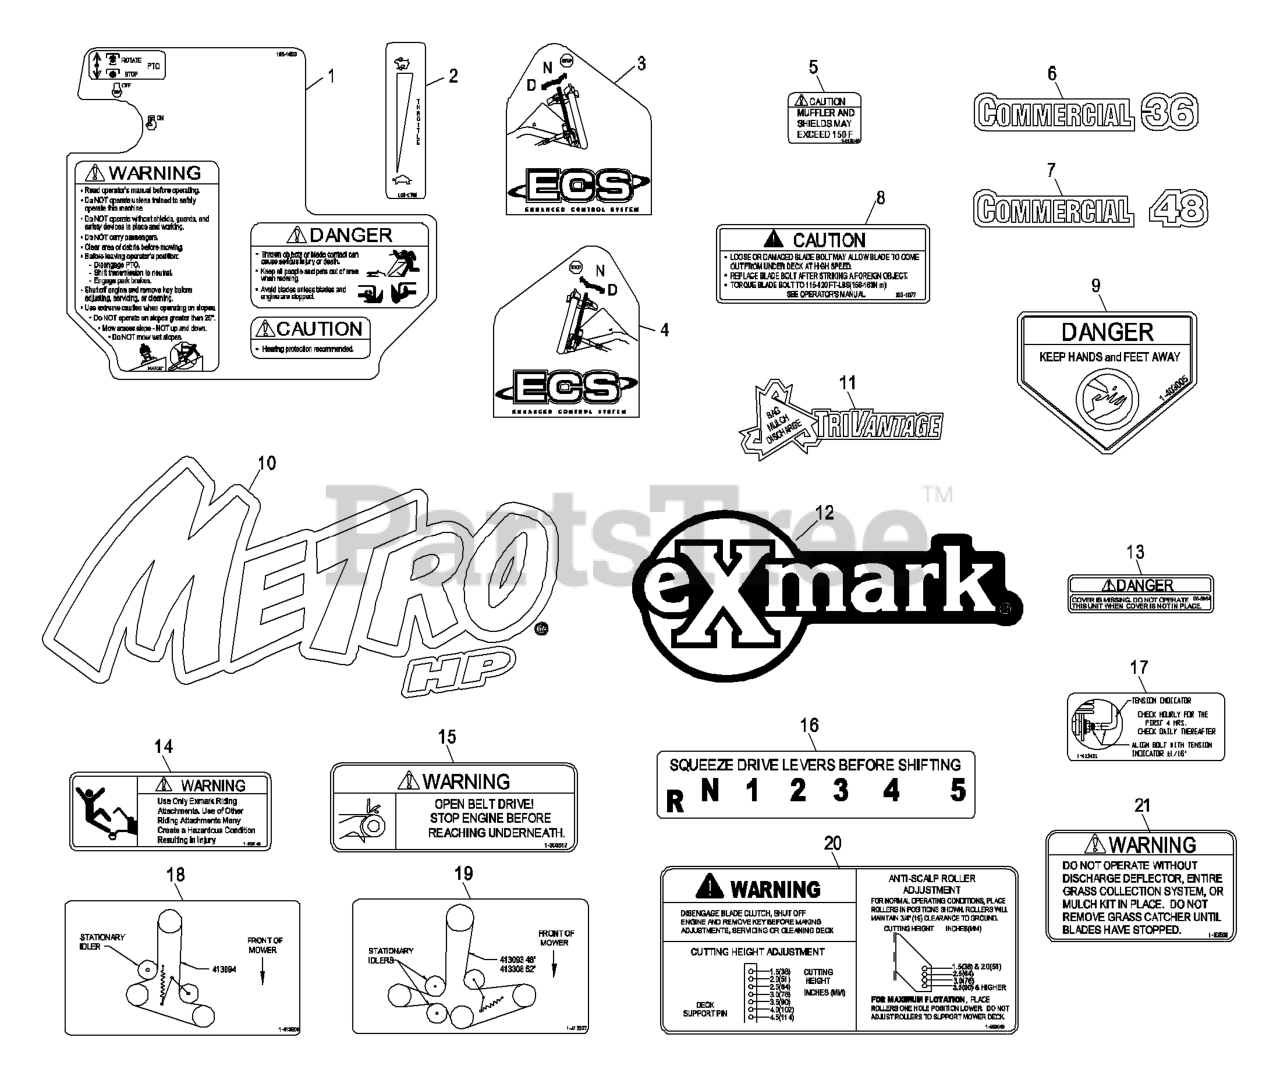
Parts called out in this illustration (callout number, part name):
1	DECAL,METRO ECS CONSOLE
2	DECAL,THROTTLE ONLY
3	DECAL,LH ECS INSTRUCTION
4	DECAL,RH ECS INSTRUCTION
6	DECAL,COMMERCIAL 36
7	DECAL,COMMERCIAL 48
8	DECAL,BOLT TORQUE
9	DECAL-DANGER
12	DECAL,EXMARK LOGO
13	DECAL-COVER, MISSING
14	DECAL,SULKY WARNING
15	DECAL,BELT DRIVE
16	DECAL,SHIFTER
17	DECAL,INDICATOR
18	DECAL,BELT ROUTING
19	DECAL,BELT ROUTING
20	DECAL,ANTI SCALP
21	DECAL-WARNING, DISCHARGE
